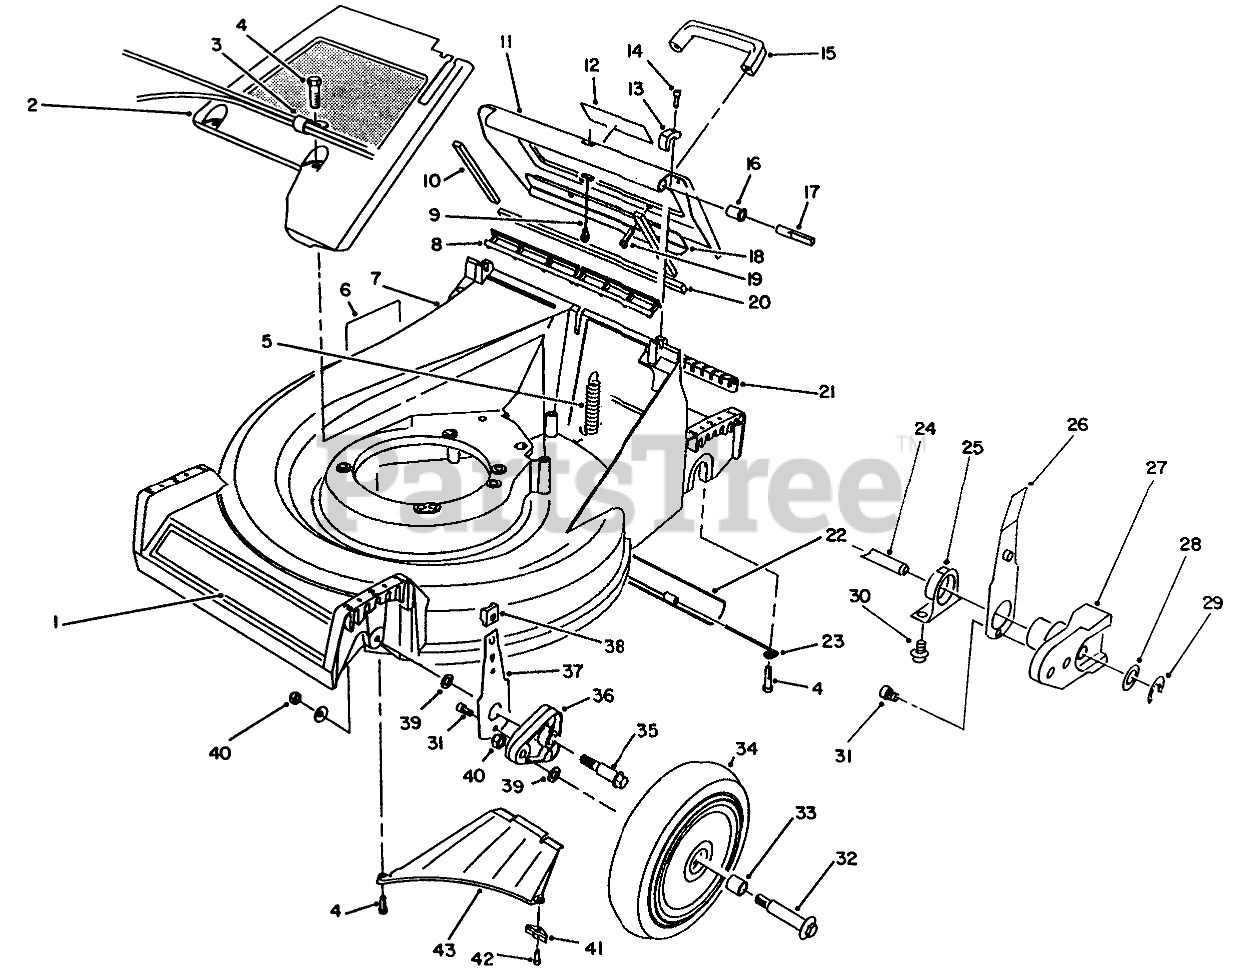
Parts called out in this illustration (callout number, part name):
1	DECAL - DECK
2	PaneI-Screen
3	CLAMP
4	SCREW-HWHTF
5	EXTENSION-SPRING
6	DECAL-DANGER
7	21" Housing Assembly (Incl. Ref. #6)
8	DOOR SEAL
9	DOOR CABLE
10	DOOR SIDE SEAL
11	Door-Discharge (Incl. Ref. #10, 12, 18 & 20)
12	DECAL - WARNING
13	HINGE CLAMP
14	SCREW-HSH
15	HANDLE-DOOR
16	DOOR BUSHING
17	HINGE PIN
18	DOOR - BRACE
19	SCREW-HWH
20	DOOR END SEAL
21	ACCESS COVER
22	SHIELD - TRAILING
23	LH SHIELD HANGER
24	SHAFT - AXLE
25	CAP-END
26	SPRING ARM ASM
27	PIVOT ARM ASM
28	WASHER-ARM, PIVOT
29	RING-RETAINING
30	SCREW-HWHTF
31	SCREW-HSH, THREAD FORMING
32	WHEEL BOLT
33	BUSHING
34	Wheel & Tire Assembly (Incl. Ref. # 33
35	BOLT-SHOULDER
36	ARM-PIVOT, FRONT
37	FRONT SPRING ARM ASM
38	KNOB-ARM
39	WASHER
40	Nut
41	Bracket-Discharge
42	SCREW-HWHTF
43	Ramp Discharge
